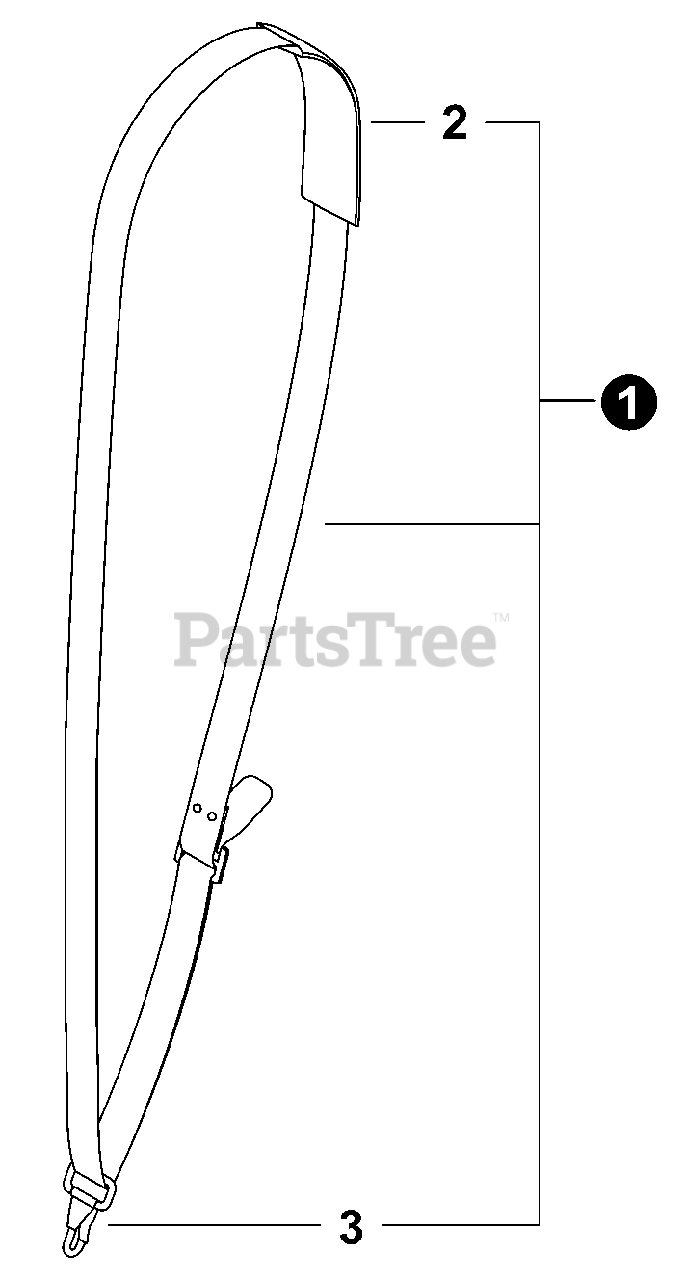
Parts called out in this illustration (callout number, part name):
1	HARNESS ASSY
2	PAD, SHOULDER
3	HOOK, SNAP
